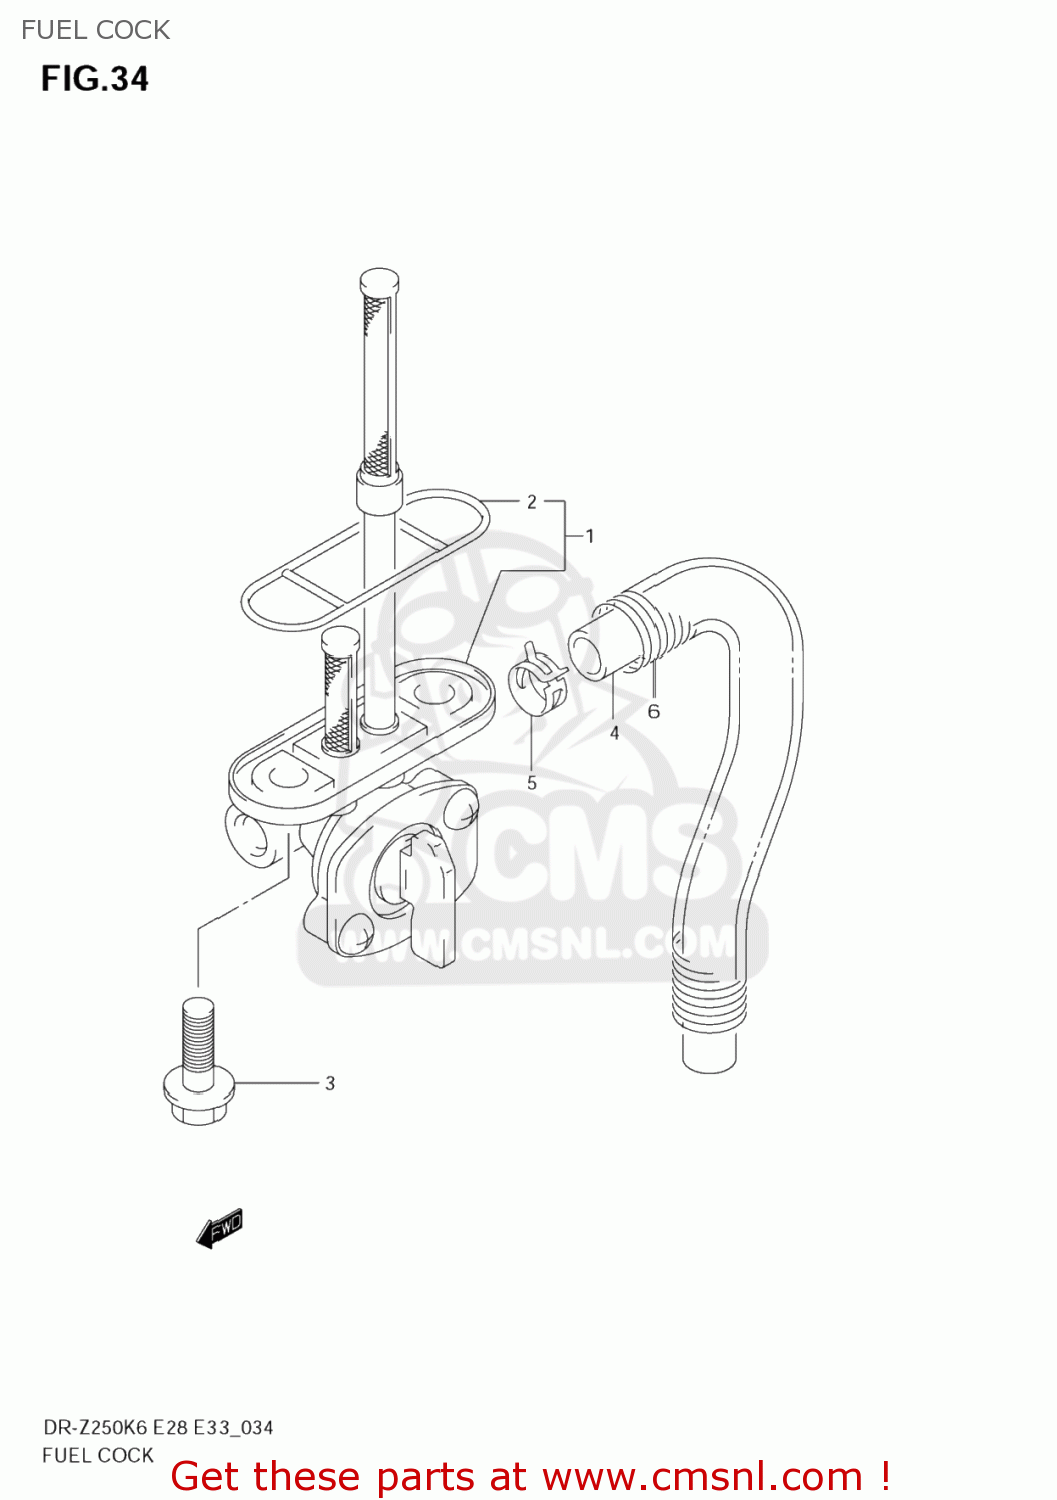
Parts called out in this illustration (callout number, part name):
1	COCK ASSY,FUEL
2	GASKET,JOINT (NAS)
3	BOLT
4	HOSE(5X10X600)
5	CLIP
6	SPRING
